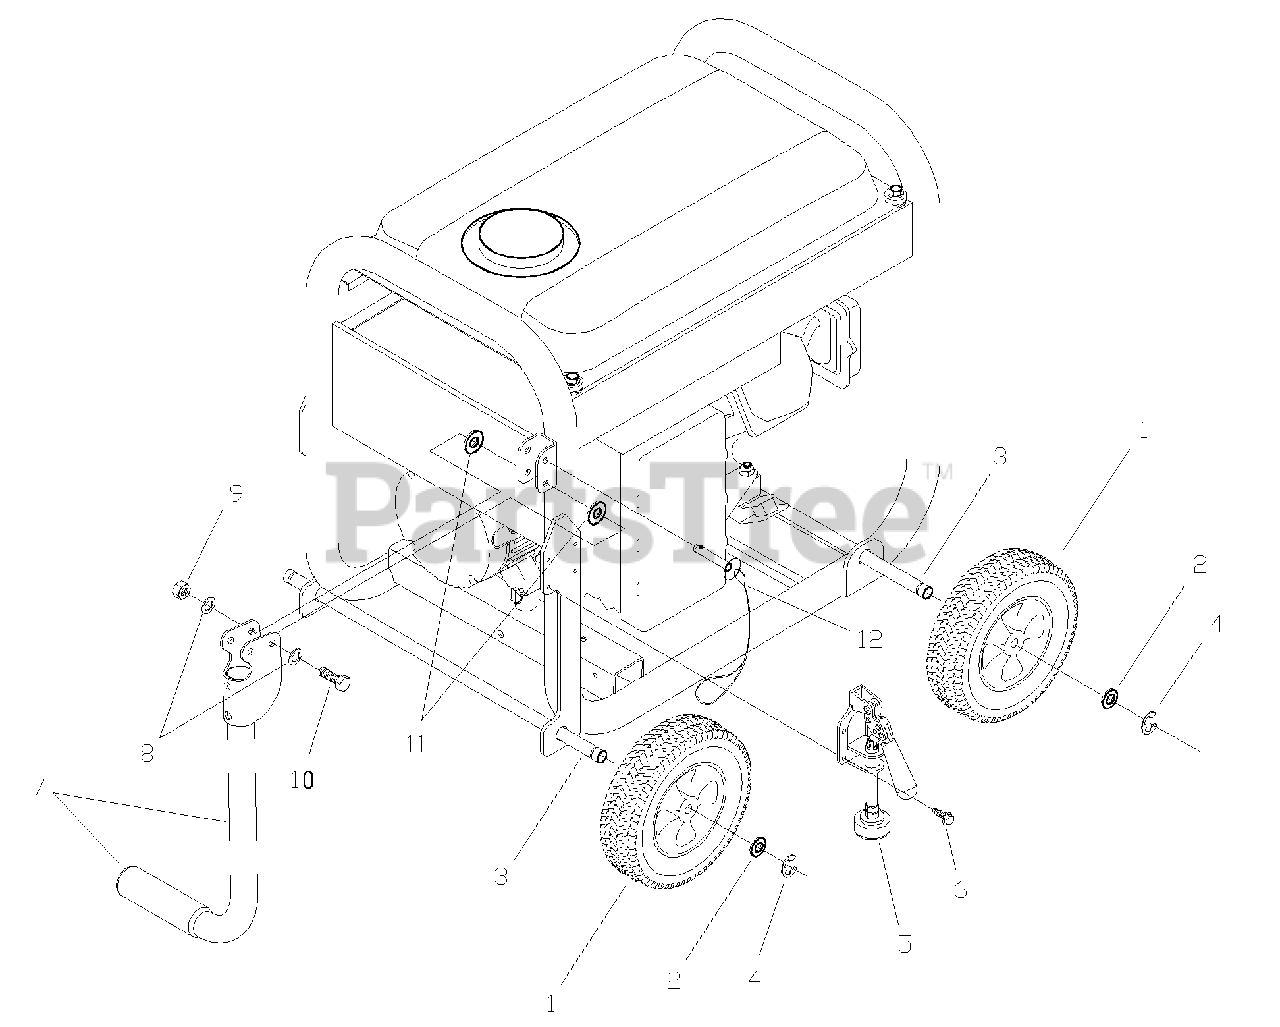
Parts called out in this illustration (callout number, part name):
2	WASHER, 5/8"
4	E-RING
6	SCREW, 1/4-20 x 3/8
7	ASSY, Handle w/Grip
8	WASHER, Flat, 5/16 - M8
9	NUT, M8 - 1.25, Nylok
10	HHCS, M8 - 1.25 x 50
11	WASHER, 1.2 x 0.346 x 0.03, Nylon
